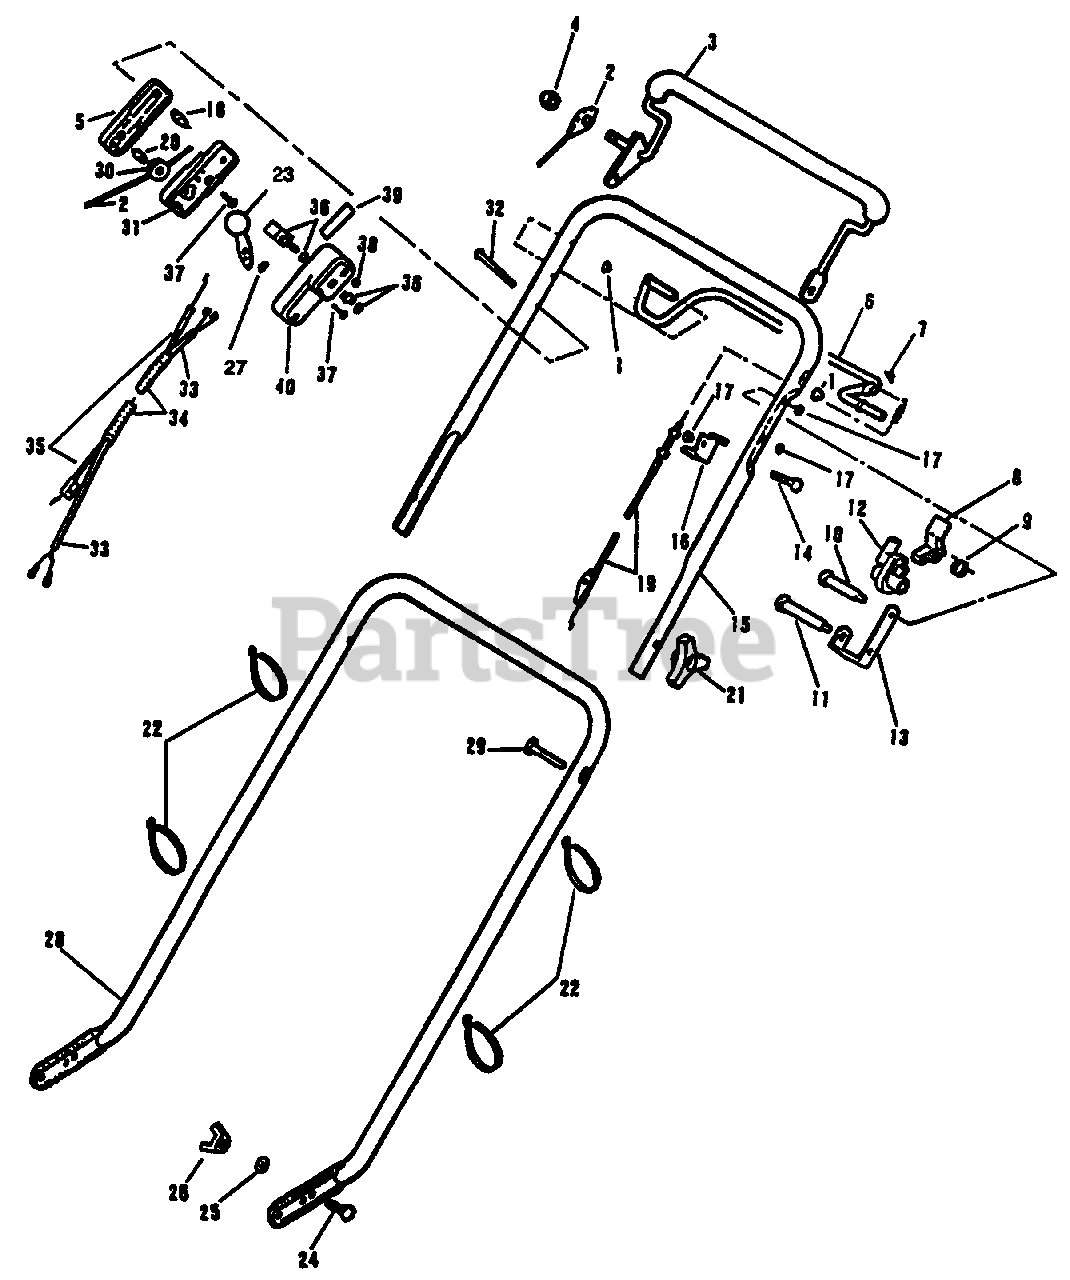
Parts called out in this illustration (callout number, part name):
1	Palnut
2	Control Cable Assembly
3	Control Lever Assembly
4	Acorn Nut
5	Control Case-Outer
6	Control Lever-Bail
7	Palnut
8	Stop-Latch Lever
9	Spring-Torsion
10	Bolt-Shoulder
11	Bolt-Shoulder
12	Cam
13	Bracket
14	Screw
15	Handle-Top
16	Conduit Anchor
17	Nut
18	Column
19	Control Cable Assembly
20	Pin-Pulley
21	Handle Knob
22	Tie Strap
23	Lever & Knob Assembly
24	Bolt
25	Washer
26	Wing Nut
27	Washer
28	Handle-Lower
29	Screw
30	Pulley
31	Throttle Case-Center
32	Screw
33	Wire Harness Assembly
34	Spiral Tubing
35	Throttle Cable
36	Switch Assembly
37	Screw
38	Nut
39	Decal-Throttle Control
40	Throttle Case-Inner
